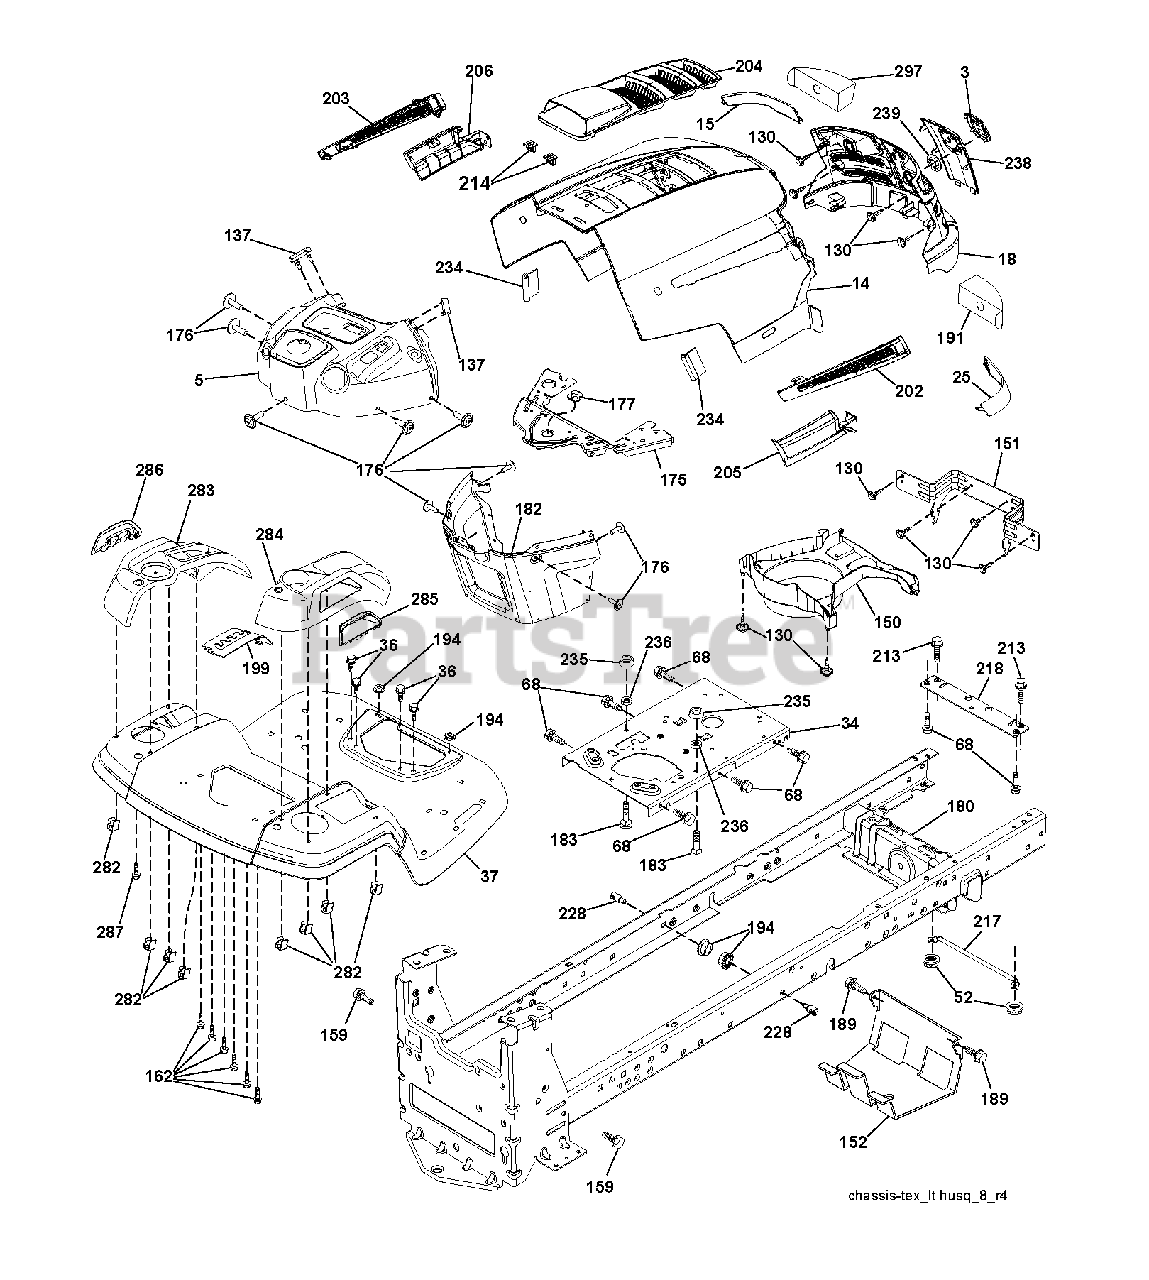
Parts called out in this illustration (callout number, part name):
3	LOGO.HUSQ.GT.LT.CROWN.H
5	SUBASM.DASH.UPPER.HLT.498
14	HOOD.HUSQVARNA.LT.ORANGE
15	LENS.HUSQVARNA LT.RH
18	GRILLE.SVC.HUSQVARNA.GREY
25	LENS.HUSQVARNA LT.RH
34	PLATE.ENGINE.WELDED.CHASSIS
36	SCREW 5/16"
37	FENDER.TLT.FS.W/CUPHLD.ORANGE
52	LOCKNUT
68	SCREW LT
130	SCREW.#10 X 0.750.BOS
137	BUMPER DASH
151	BRACKET PIVOT
152	SHIELD.BROWNING.W/TEX
159	SCREW, 3/8-16X3/4
162	SCREW.HI-LO.CONSOLE
175	CROSSMEMBER
176	SCREW.#10-24X5/8.RN.QU
177	BUSHING STEERING
180	CHASSIS
182	DASH.LOWER.PREDATOR LT
183	BOLT.5/16-18X1-1/4 FULL THD
189	SCREW
191	INSERT.REFLECTIVE.RH.
194	NUT LOCK HEX FLANGE 5/16-18
199	PLATE.DECK.LIFT.HUSQ.LT
202	VENT.SIDE.HUSQVARNA.LT.RT
203	VENT.SIDE.HUSQVARNA.LT.LFT
204	SUBASM.TOP.VENT.HUSQ.LT
205	SKIRT.SIDE.HUSQVARNA.LT.RT
206	SKIRT.SIDE.HUSQVARNA.LT.LEFT
213	BOLT
214	CLIP.RETAINER.TINNER.
217	ROD.PIVOT.HOOD
218	X-PIECE.HOOD.STOP.NON/
228	STUD.FASTNER.W/ANTI-ROTATE
234	BUMPER.HOOD.TEX.HUSQVARNA
235	SPACER FENDER
236	NUT.CENTERLOCK.5/16-
238	TRIM.HUSQ LT.668
282	CLIP.RETAINER.CONSOLE.LT.HUSQ
283	CONSOLE.ASM.LFT.RSF.HUSQ.LT
284	CONCOLE.CNTRL.PDL.HUSQ.LT.498
285	CONSOLE INSERT RH
286	CONSOLE.INSRT.LH.HUSQ.LT.BLACK
287	SCREW 1/4X20
297	INSERT REFLECTIVE
